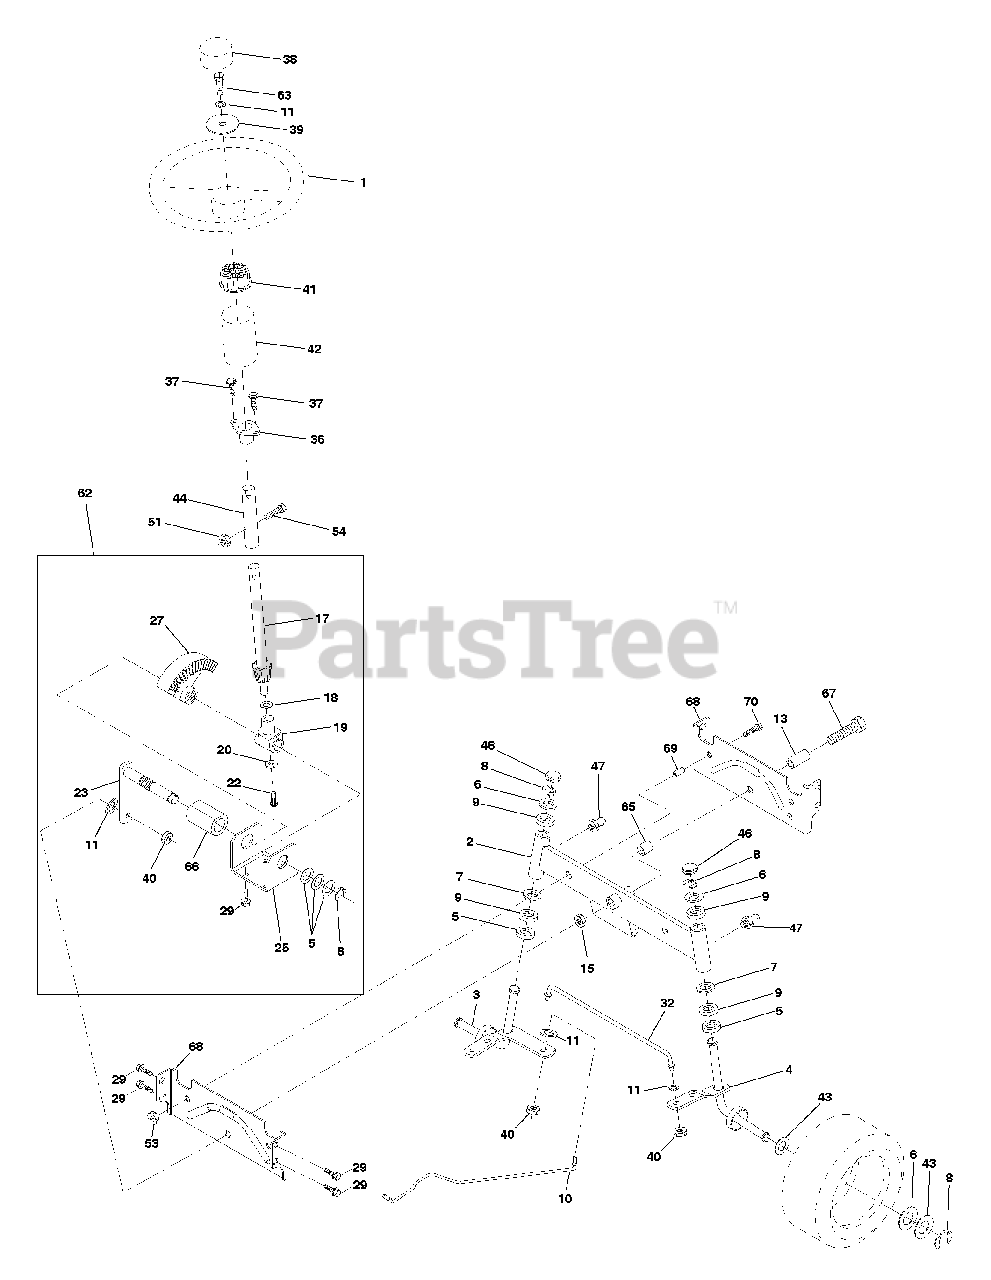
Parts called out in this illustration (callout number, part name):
1	Wheel Steering
2	Axle Front Casting Machined
3	Spindle Asm LH Cast 15"
4	Spindle Asm RH Cast 15"
5	Bearing Race Thrust Harden
6	Washer 25/32 X 1-5/8 X 16 Ga
7	Washer 27/32 X 1-1/4 X 16 Ga
8	Ring Klip #t5304-75
9	Bearing Col Strg Blk
10	Link Drag Extended Cast
11	Washer Lock Hvy Hlcl Spr 3/8
13	Bearing Axle STLT/GT
15	Nut Lock Flange 5/8-11 Unc
17	Shaft Asm Strg
18	Washer Thrust 515 x 750 x 033
19	Support Shaft
20	Washer Shim 1/4 X 5/8 X 062
22	Screw Hex Socket 1/4-20 x 5/8
23	Shaft Asm Pittman
25	Bracket Steering
27	Gear Sector
29	Screw Thdrol 3/8-16 x 3/4 Ty-tt
32	Rod Asm Tie Ball J Adj VGT
36	Bushing Strg
38	Insert Cap Strg Wh Au
39	Washer 13/32 X 2-3/8 X 8 Ga
40	Lock nut
41	Adaptor Wheel Strg
42	Boot Steering Shaft
43	Washer 25/32 X 1 1/4 X 16 Ga
44	Extension Steering Shaft LR/LT
46	Cap Spindle Fr Top Blk
47	Fitting Grease
51	Nut Lock Hex w/Ins 5/16-18
53	Nut Crownlock 3/8-16 UNC
54	Bolt Fin Hex 5/16-18 Unc x 1-1/4
62	Kit, Steering Assembly Svc
63	Bolt Fin Hex 3/8-16 unc x 1 Gr. 5
65	Spacer Axle
66	Bearing Arm Pittman
67	Bolt, Fin Hex 5/8-11 UNC x 2-3/4
68	Axle, Brace
69	Spacer Brace Axle
70	Bolt Fin Hex 3/8-16 UNC x 2-1/4
